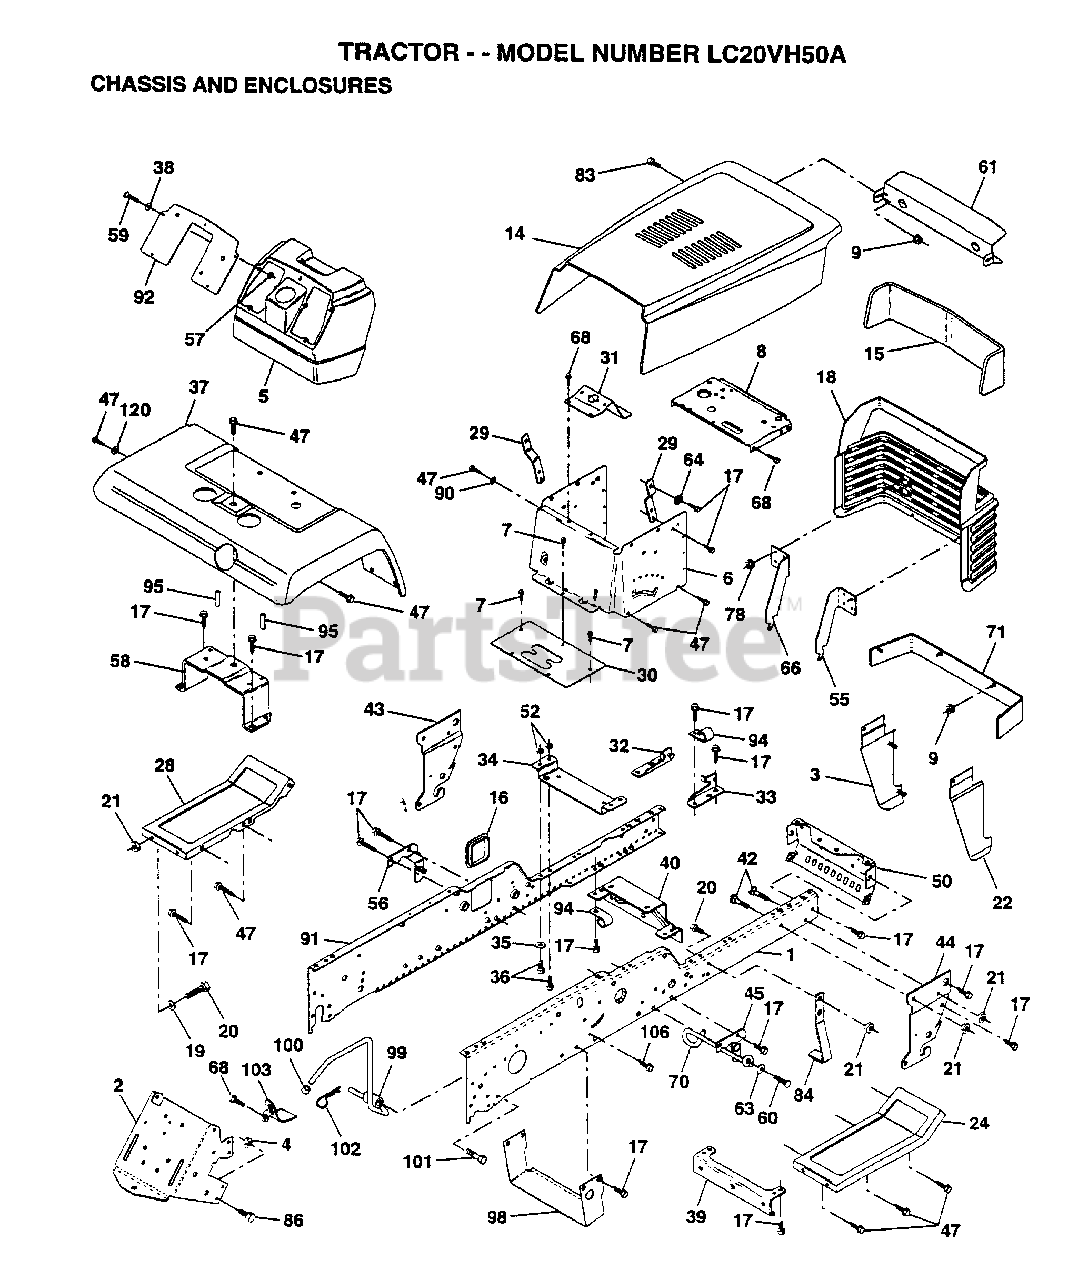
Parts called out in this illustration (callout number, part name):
2	DRAWBAR GT
3	PANEL.SIDE.LH.ASN
4	NUT.7/16
5	DASH.PLASTIC.BLK
6	DASH.1PC.LOWER
7	SCREW
8	SUPPORT.DASH.BTRY
9	PAL NUT LT
14	HOOD.ASM.YTGT.PNT
16	COVER ACCESS
17	SCREW
18	GRILLE ASM WELD
19	WASHER
20	BOLT
22	PANEL.SIDE.RH.ASM
24	FOOTREST.RH.LT/GT
28	FOOTREST.LH.LT/GT
29	BRACKET.SUPT.DASH
30	SADDLE.HYDRO.95
31	BRAKET.SUPT.STEER
32	BRACKET ASM FRAME
33	BRACKET ASM FRAME
34	BRACKET.ENG.SUPT.
35	WASHER
36	BOLT
37	FENDER.PNT.
38	WASHER PM
39	BRACKET.AXLE.FRT.
41	SCREW CRT
43	BRACKET.SUS.FT.LH
44	BRACKET.SUS.FT.RH
47	SCREW LT
50	BRACKET.CHASSIS.
55	BRACKET.PICK.RH
57	NUT
58	BRKT.ASM.FENDER
59	SCREW
60	SCREW
63	WASHER
64	WASHER.SERRATED.
68	SCREW LT
70	GUIDE.BELT.MID.SP
78	PAL NUT
83	SCREW SPECIAL
84	STOP.OVER.CENTER
86	BOLT
90	LOCKWASHER
92	PLATE.DASH.SILKSC
94	CLIP GTV
95	NUT-PUSH YT
98	BRACKET SKID CHAS
99	ROD BYPASS
101	SCREW LT
102	RETAINER M
103	LOCK BYPASS BRKT
120	WASHER HYT
